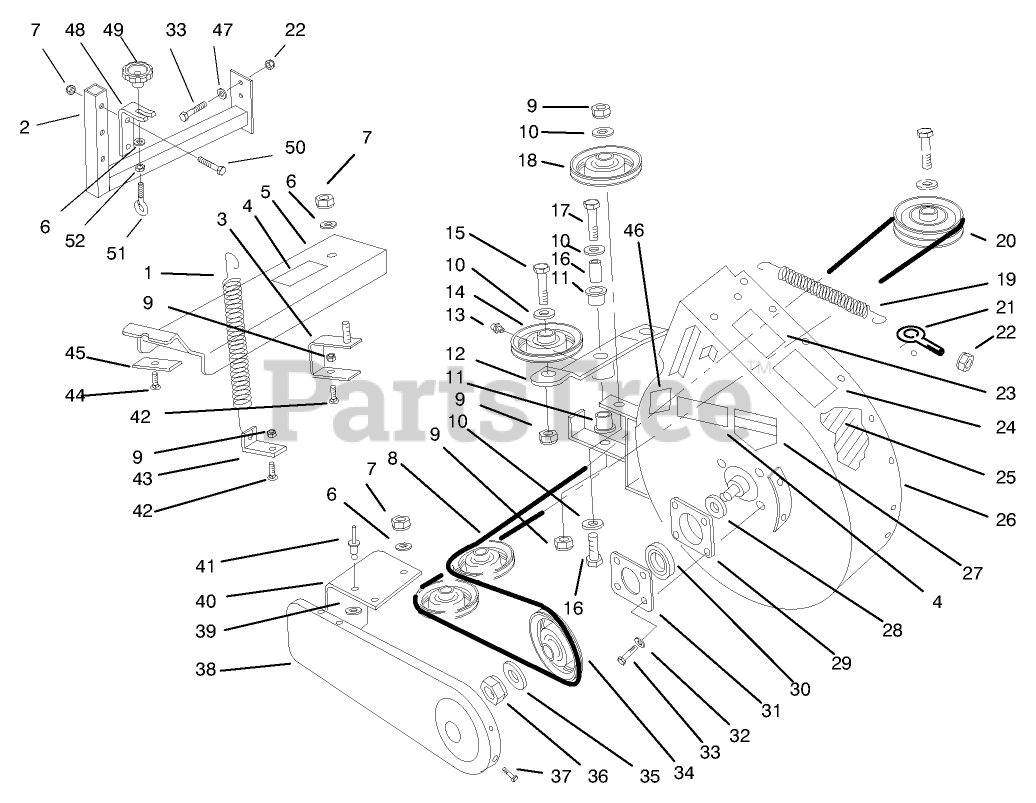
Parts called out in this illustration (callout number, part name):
1	SPRING-EXTENSION
2	WA - BRACKET
3	BRACKET-SHIELD B
4	DECAL-DANGER
5	COVER-BELT B
6	WASHER-PLAIN
7	NUT-LOCK, NI
8	BELT-V
9	NUT-LOCK, NI
10	WASHER-FLAT
11	BUSHING
12	ARM-IDLER-WELDED B
13	FITTING-GREASE
14	PULLEY-IDLER, FLAT
15	SCREW-HH
16	SPACER
17	SCREW-HH
18	PULLEY-IDLER
19	SPRING
20	PULLEY - DRIVE BLOWER
21	EYE BOLT
22	NUT-LOCK, NI
23	DECAL-DANGER
24	DECAL - WARNING
25	STRIP-WEAR
26	BLOWER ASM W/DECALS
27	DECAL-DANGER
28	SPACER-BEARING
29	CUP-BEARING
30	BEARING-BALL
31	Cover-Plate
32	WASHER-LOCK
33	SCREW-HH
34	PULLEY-BLOWER R
35	WASHER-FLAT
36	NUT 5/8-11 L.H.
37	SCREW
38	SHIELD-PULLEY B
39	WASHER-FLAT
40	SHIELD
41	RIVET-BLIND
42	SCREW-HH
43	CLIP - SPRING
44	SCREW-CARR
45	STRAP B
46	Decal
47	WASHER-LOCK
48	PLATE - SUPPORT
50	SCREW-HH
51	BOLT-EYE
52	NUT-HEX
